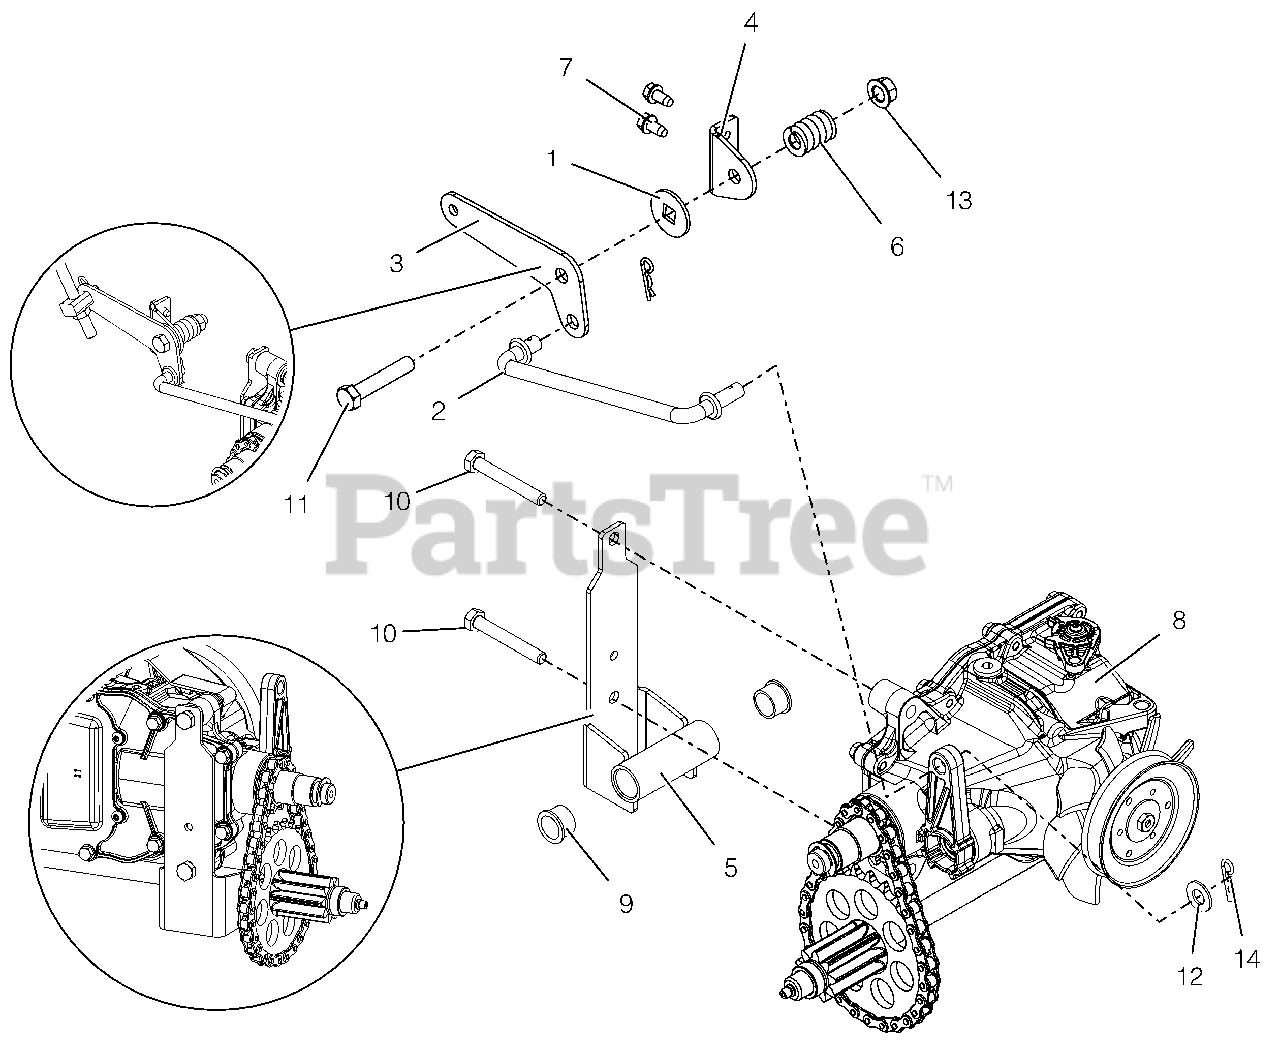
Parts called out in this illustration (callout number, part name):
1	FRICTION WASHER
2	ROD, HYDRO TRANS SHIFT
3	PIVOT, HYDRO TRANS SHIFT
4	BRACKET, HYDRO SHIFT PIVOT
5	TRANS MOUNT, TENSIONING, WHEEL
6	SG-COMP .187X.56X1.62
7	SCR-TAP .25-20X.50 HWH TR YWZ
8	TRANSMISSION, HYDROSTATIC
9	BSHG-FLG .625X.750X.500X.875
10	@BLT-HEX .31-18X2.25 GR5 YWZC
11	@BLT-HEX .38-16X2.00 GR5 YWZC
12	@WSHR-FL-STL.406X.812X.065 YWZ
13	@NUT-LK-TOP-FLG .38-16 YWZC
14	PIN-HAIR INT .08X.18X1.18 YWZC
